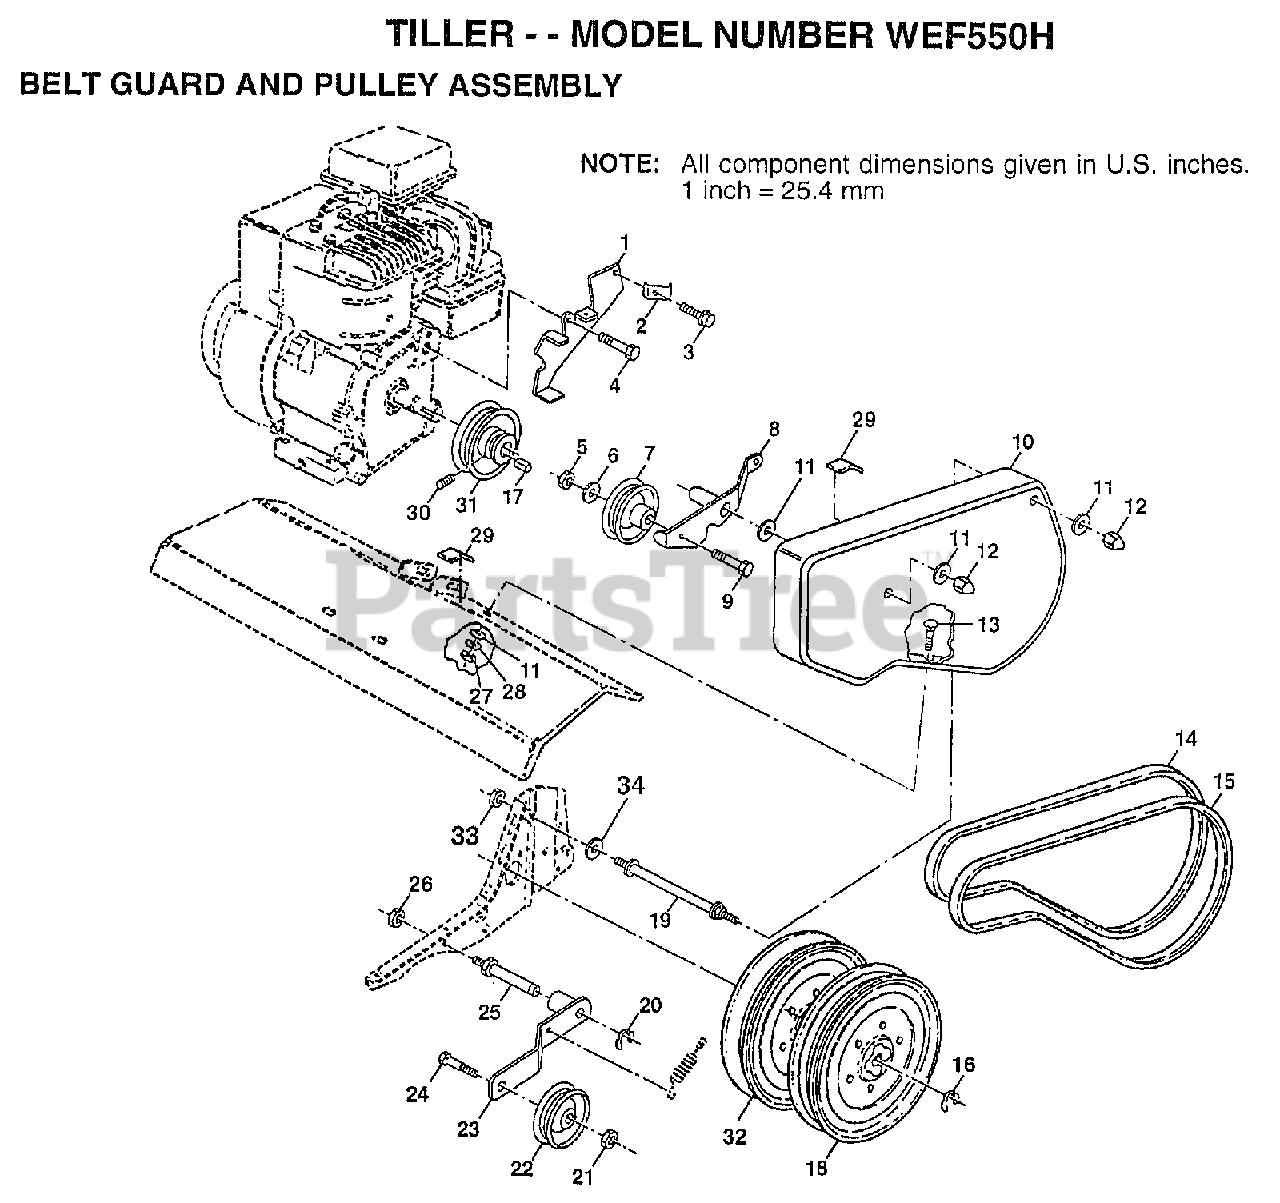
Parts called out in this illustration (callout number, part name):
1	ASM.BRKT.BELT.GRD
2	CONDIUT CLIP T
4	BOLT.HEX.HEAD
5	NUT.HEX.3/8-16UNC
6	WASHER
7	PULLEY W/SPACER
8	ARM.ASM.REV.IDLER
10	"GUARD,BELT"
11	WASHER
12	NUT-CAP TI
13	BOLT T
14	BELT-V
17	KEY T
18	"SHEAVE,TRANS.""D"""
19	BOLT TI
20	KLIP RING TI
21	NUT
23	IDLER ARM TI
25	SHAFT IDLER TI
26	JAM NUT TI
28	LOCKWASHER
29	PAD IDLER TI
30	SET SCREW
31	ENGINE PULLEY TI
32	SHEAVE.TRANS
33	NUT
34	WASHER
